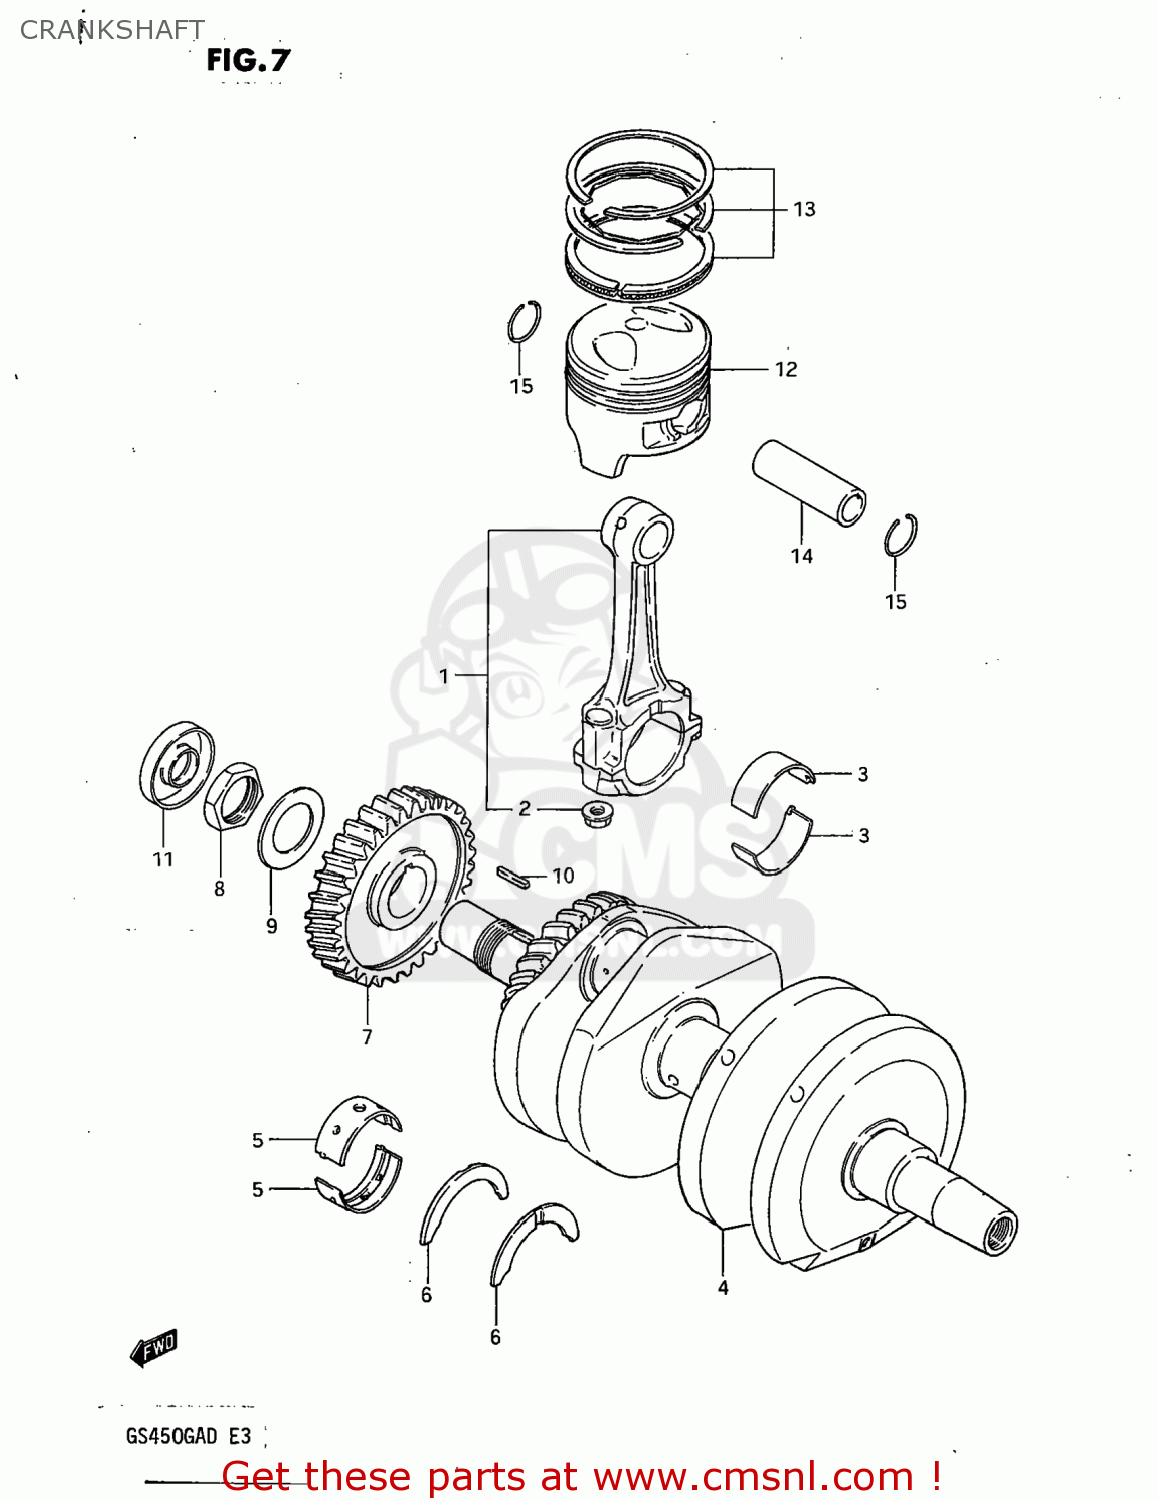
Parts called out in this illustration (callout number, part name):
1	CONNECTING ROD ASSEMBLY
2	NUT
3	BEARING,CRANK PIN
4	CRANKSHAFT
5	METAL CRANKSHAFT
6	PLATE,CRANK THRUST
7	GEAR,PRIMARY DRIVE
8	NUT
9	WASHER
10	KEY
11	OIL SEAL
12	PISTON
13	RING SET,PISTON
14	PIN,PISTON (18MM)
15	CIRCLIP
